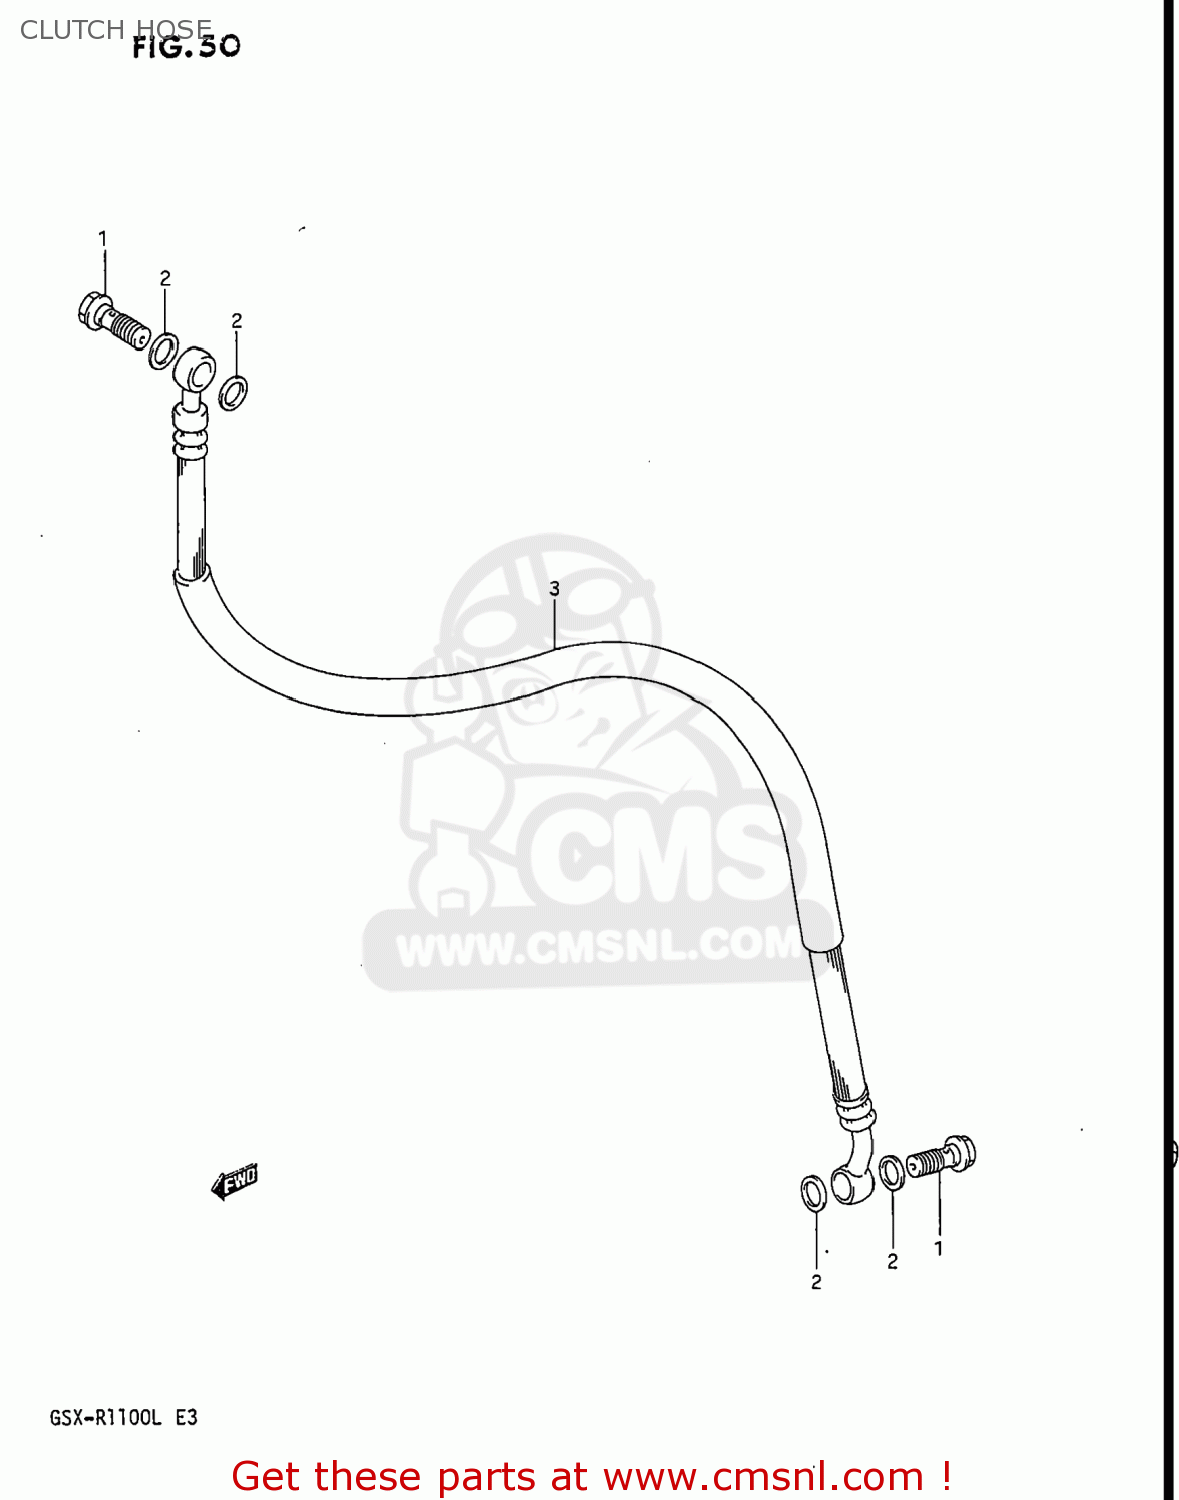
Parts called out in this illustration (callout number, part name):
1	BOLT UNION
2	WASHER(10X15X1.5)
3	HOSE,PROTECTOR
